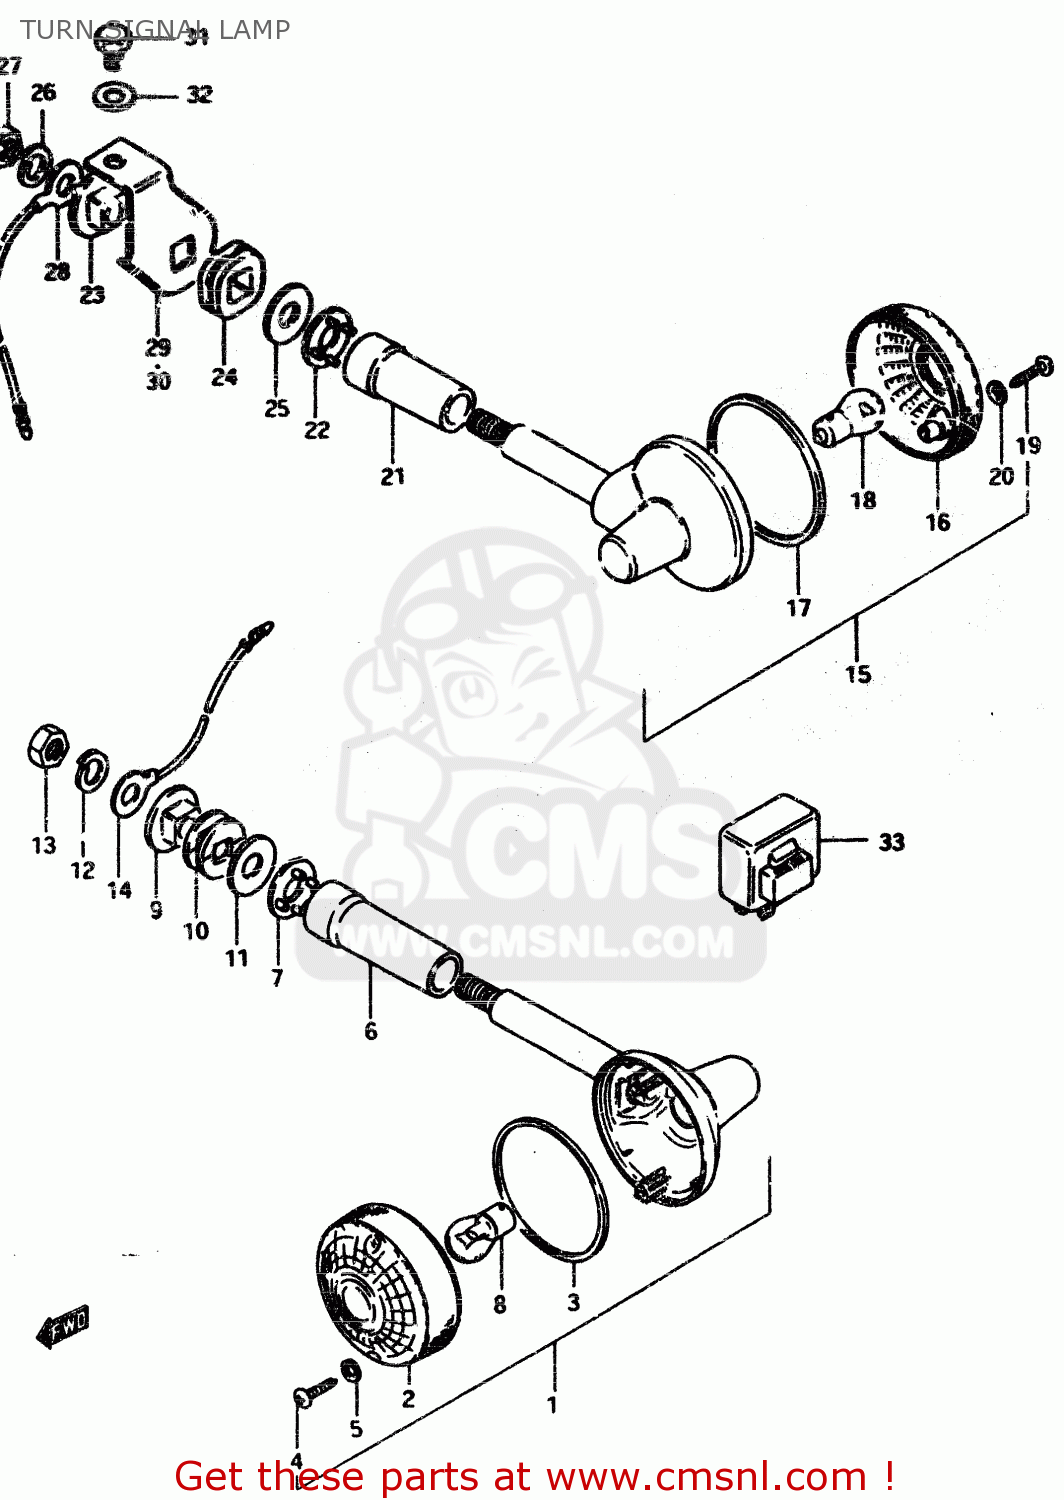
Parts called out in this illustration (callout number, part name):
1	LAMP ASSY FRON
2	LENS
3	GASKET (NAS)
4	SCREW
5	GASKET (NAS)
6	COVER,STAY
7	SPACER
8	BULB(12V21W)
9	SPACER
10	CUSHION
11	WASHER (10.5X30X2.3)
12	LOCK WASHER
13	NUT
14	LEAD WIRE,EARTH
15	LAMP ASSY,RR TURNSIGNAL
16	LENS
17	GASKET (NAS)
18	BULB(12V21W)
19	SCREW
20	GASKET (NAS)
21	COVER,STAY
22	SPACER
23	SPACER
24	CUSHION
25	WASHER (10.5X30X2.3)
26	LOCK WASHER
27	NUT
28	LEAD WIRE,EARTH
29	BRACKET,RR TURNSIGNAL LAMP,R
30	BRACKET,REAR TURN SIGNAL
31	BOLT 8X12
32	WASHER
33	RELAY,TURN SIGNAL
